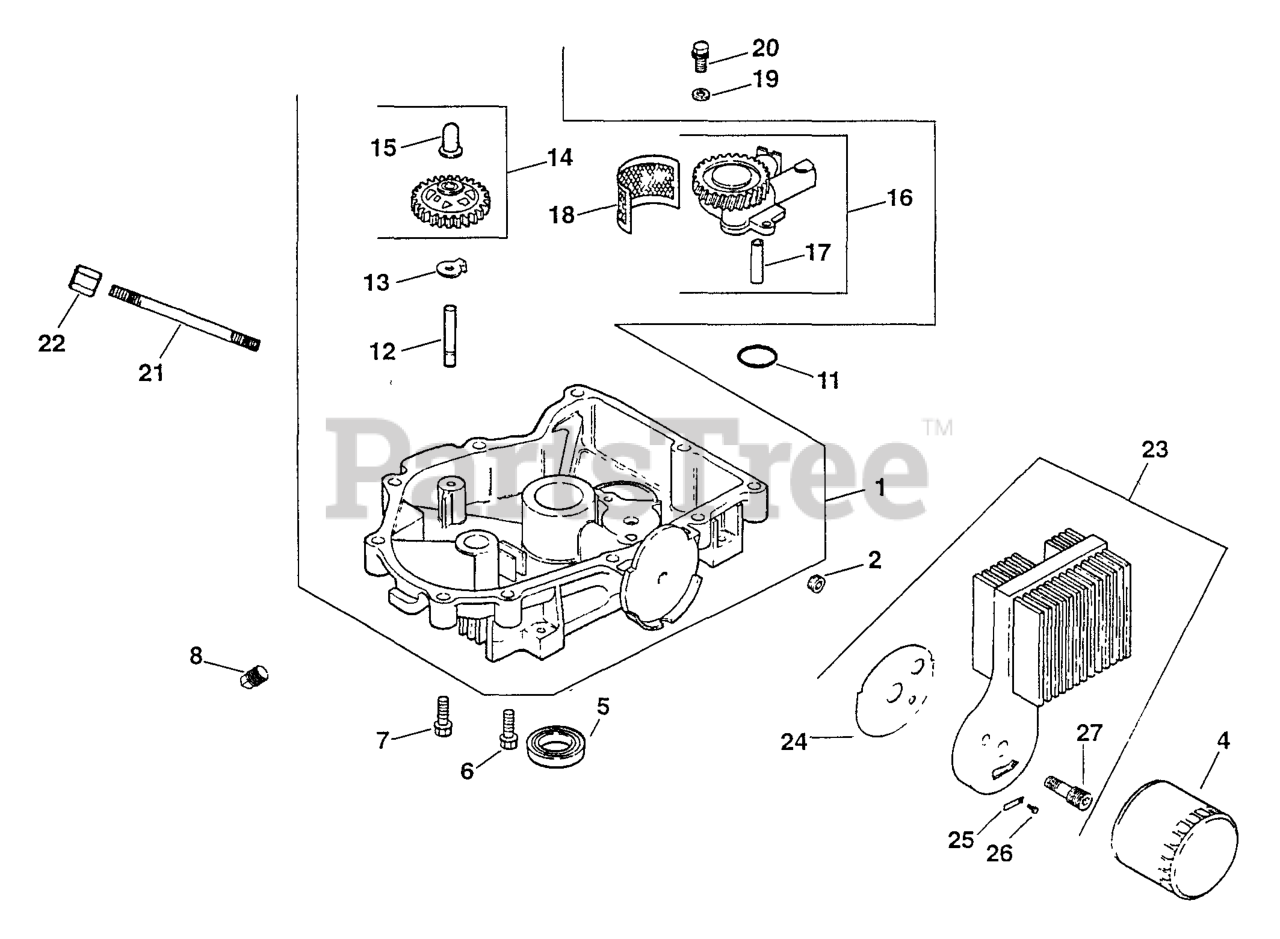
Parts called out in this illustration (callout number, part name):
1	Oil Pan Assembly
2	Plug, Allen Hd. 3/8"
4	Filter, Oil
5	Seal, Oil (Pto End)
6	Screw, Hex. Flange M8x1.25x45
7	Screw, Hex. Flange M8x1.25x45
8	Plug, Sq. Hd. Solid 3/8" N.P.T.F.
12	Shaft, Governor Gear
13	Tab, Locking
14	Kit, Governor Gear W/ Pin
15	Pin, Governor Regulating
16	Oil Pump Assembly (13 Mm)
16	Oil Pump Assembly (17 Mm)
17	Tube, Oil Pickup
18	RING-HANDLE LOCK
19	Washer, Plain 6 Mm
20	Screw, Hex. Flange M6x1.0x25
23	Kit, Oil Cooler
24	Gasket, Oil Filter Adapter
25	Reed, Oil Relief
26	Screw, Hex. Cap M4x0.7x10
27	Nipple, Oil Filter
